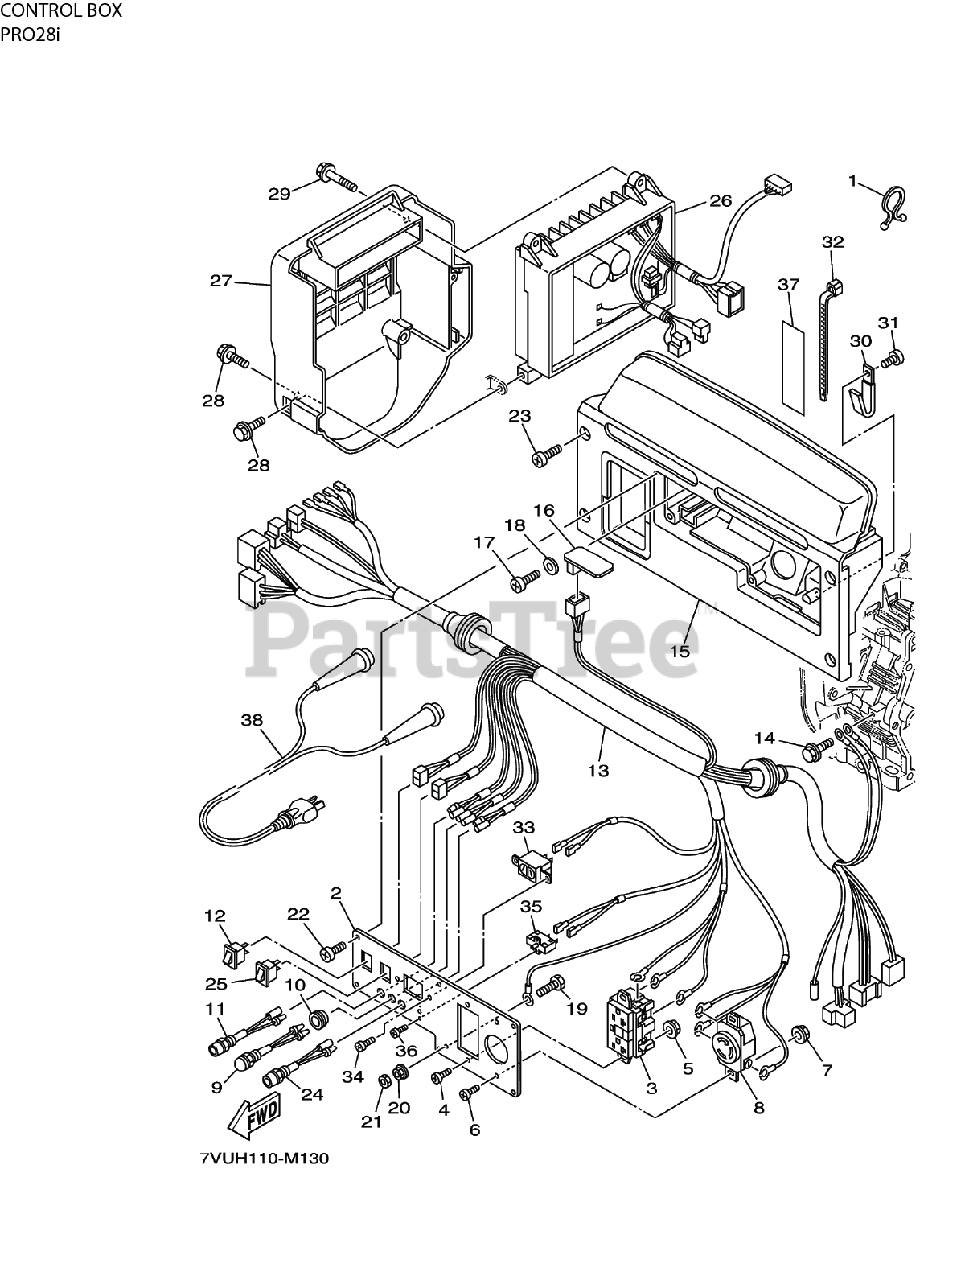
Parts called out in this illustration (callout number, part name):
2	PIN, FLOAT
3	REED, RECEPTACLE
4	SCREW - PAN HEAD
5	NUT, FLANGE
6	SCREW - PAN HEAD
7	NUT, FLANGE
8	REED, RECEPTACLE (L5-30R)
9	INDICATOR - PILOT LIGHT ASSEMBLY
11	INDICATOR - OIL PILOT LIGHT ASSEMBLY
12	SWITCH, ENGINE STOP ASSEMBLY
13	HARNESS ASSEMBLY - WIRE
14	SCREW - BOLT FLANGE
15	HOUSING - COVER, CONTROL BOX
16	CONTROL, OIL WARNING UNIT
17	SCREW - TAPPING
18	WASHER, PLATE
19	SCREW - BOLT
20	NUT, FLANGE
22	SCREW - TAPPING
23	SCREW - BIND
24	INDICATOR - PILOT LIGHT ASSEMBLY
25	SWITCH, ENGINE STOP ASSEMBLY
26	ECU, GENSET
27	COVER, AIR CLEANER - CONTROL BOX
28	SCREW - BOLT FLANGE
29	SCREW - BOLT FLANGE
33	RECEPTACLE
34	SCREW - PAN HEAD
35	BREAKER, CIRCUIT COMP
36	SCREW - PAN HEAD
37	KNOB - LEVER, COCK
38	EXTENSION CORD
